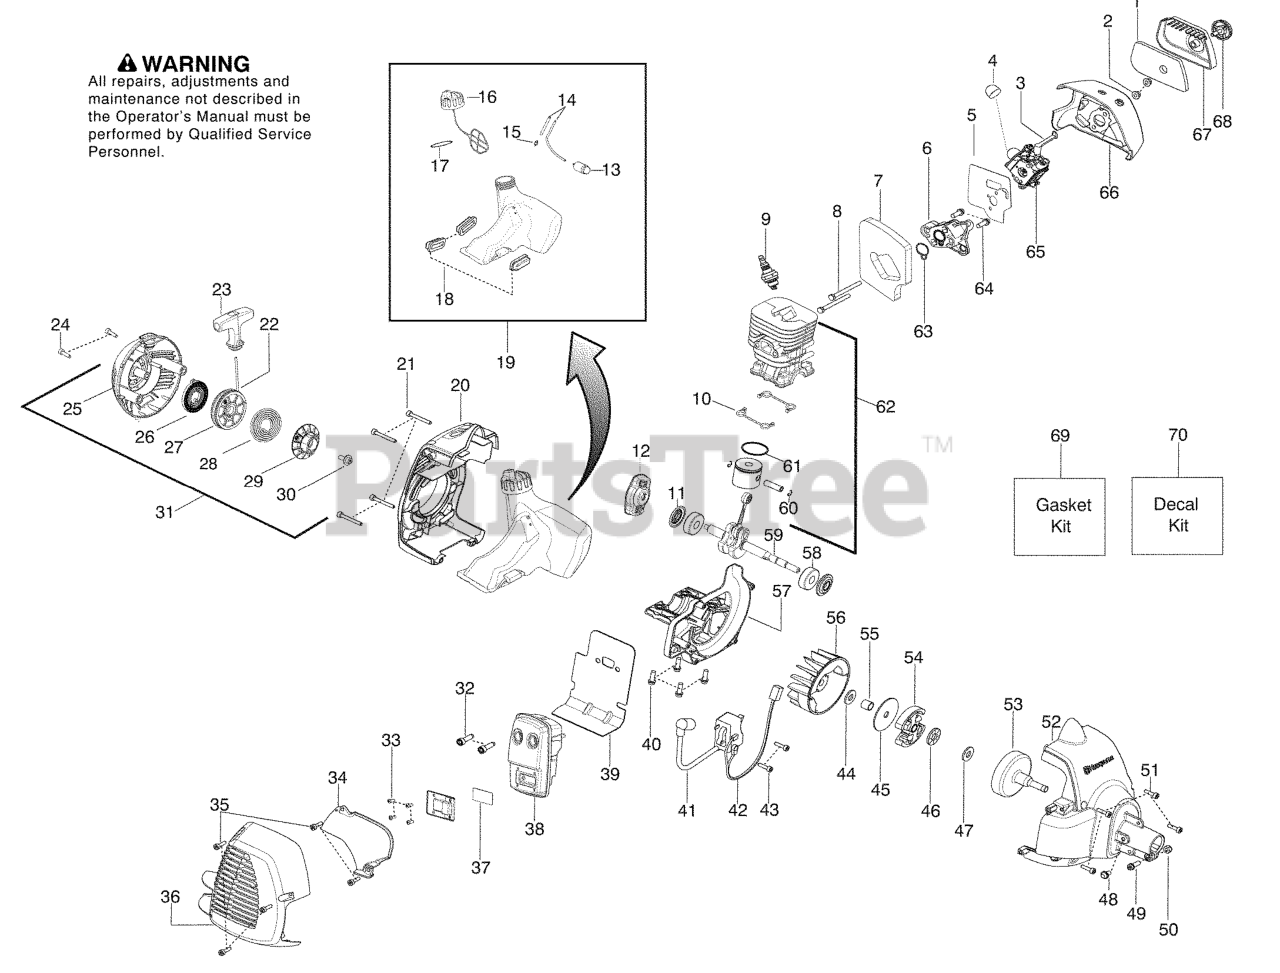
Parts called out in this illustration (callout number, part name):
1	FILTER AIRBOX
3	CHOKE LEVER
4	PURGE BULB ZAMA
5	KIT GASKET CARB 28CC
6	CARB ADAPTOR
7	KIT GASKET 28CC
8	BOLT CARB ADAPTOR
9	Plug - Spark
10	KIT GASKET 28CC
11	KIT GASKET 28CC
12	STARTER PAWL BRIDGE
13	FUEL PICK-UP ASSY
14	KIT-LINE(FUEL)
15	FUEL LINE FITTING
16	ASSY-CAP W/RETAINER
17	KIT GASKET 28CC
18	ISOLATOR FUEL TANK
19	KIT FUEL TANK HVA
20	REAR SHROUD
22	KIT ROPE
23	STARTER HANDLE
24	SCREW M5-0.8X30MM
25	HSG STARTER W/EYELET
26	KIT STARTER SPRING
27	KIT STARTER PULLEY
28	SPRING - DRIVER
29	DRIVER PULLEY
31	ASSY STARTER HSG
32	BOLT MUFFLER
33	SCREW-6-19X5/16PLAST PA
34	SHIELD HEAT
35	SCREW M4 X 1.75 PT 16MM
36	GUARD-MUFFLER
37	KIT SPARK ARRESTOR SCREEN
38	KIT MUFFLER LE28
39	KIT GASKET 28CC
40	SCREW-M5-0.8 X 25MM(TAP)
41	IGNITION MODULE MBU-7
42	ASSY MODULE LEAD WIRE
43	SCREW M4 X .70 TT 16MM
44	WASHER CLUTCH
45	WASHER-CLUTCH
46	BEARING THRUST
47	WASHER THRUST
50	LOCKNUT-HEX 10-24
51	SCREW M4 X .70 TT 16MM
52	FAN HSG ASSY
53	ASSY-CLUTCH DRUM
54	ASSEMBLY CLUTCH
55	SPACER FLYWHEEL
57	CRANKCASE CAST LE28
58	BEARING RADIAL BALL (6201)
59	ASSY CRANKSHAFT
60	WRIST PIN RET.
61	RING PISTON
62	KIT PISTON & CYLINDER
63	KIT GASKET 28CC
64	SCREW-M5-0.8 X 25MM(TAP)
65	CARBURETOR KIT W38
66	RP_AIR BOX
67	COVER-AIR BOX
68	KNOB ASSY AIRBOX COVER
69	KIT GASKET 28CC
